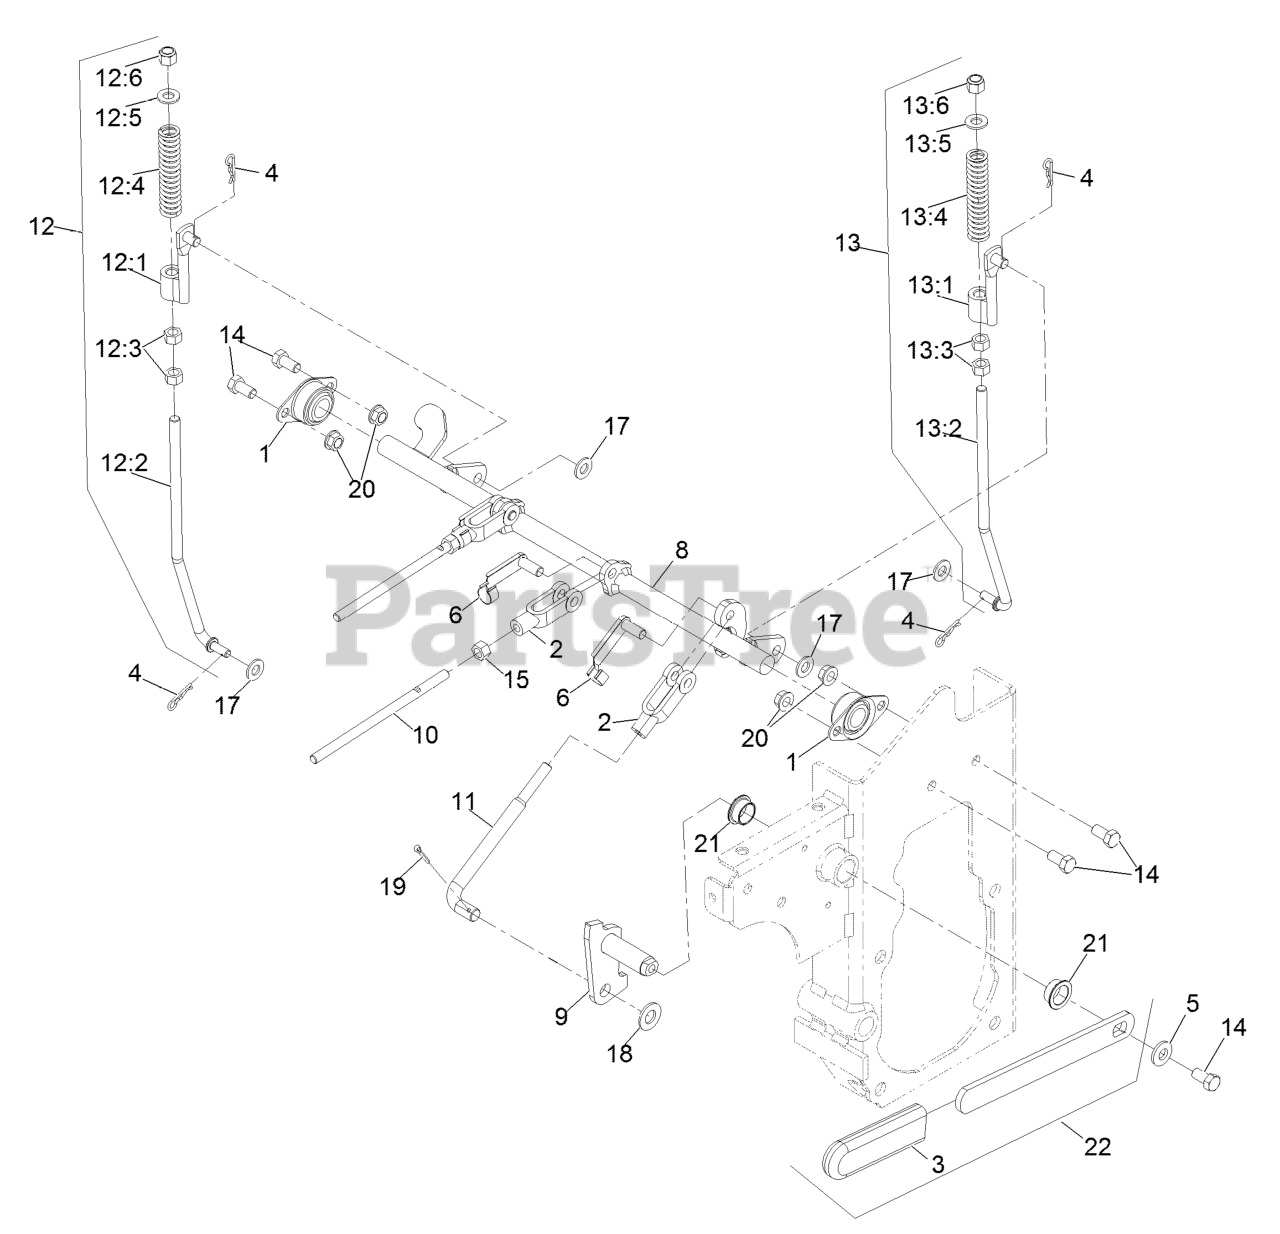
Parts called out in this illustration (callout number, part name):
1	BEARING-FLANGE, SIDE
2	YOKE-LINKAGE, BRAKE
3	GRIP-LEVER
4	PIN-COTTER
5	WASHER-BELLEVILLE
6	PIN-SPRING, CLEVIS
8	SHAFT-BRAKE
9	PIVOT-BRAKE
10	ROD-LINKAGE, BRAKE
11	ROD-LINKAGE, BRAKE
12	RH BRAKE LINKAGE ASM
12:1	BRAKE LINKAGE ASM
12:2	LINK-BRAKE, RH
12:3	NUT-HEX
12:4	SPRING-COMPRESSION
12:5	WASHER-FLAT
12:6	NUT-LOCK
13	LH BRAKE LINKAGE ASM
13:1	BRAKE LINKAGE ASM
13:2	LINK-BRAKE, LH
13:3	NUT-HEX
13:4	SPRING-COMPRESSION
13:5	WASHER-FLAT
13:6	NUT-LOCK
14	SCREW-HH
15	NUT-HEX
17	WASHER-FLAT
18	WASHER-FLAT
19	PIN-COTTER
20	NUT-HHF, WHIZ
21	BUSHING-BRONZE
22	PARK BRAKE HANDLE ASM
